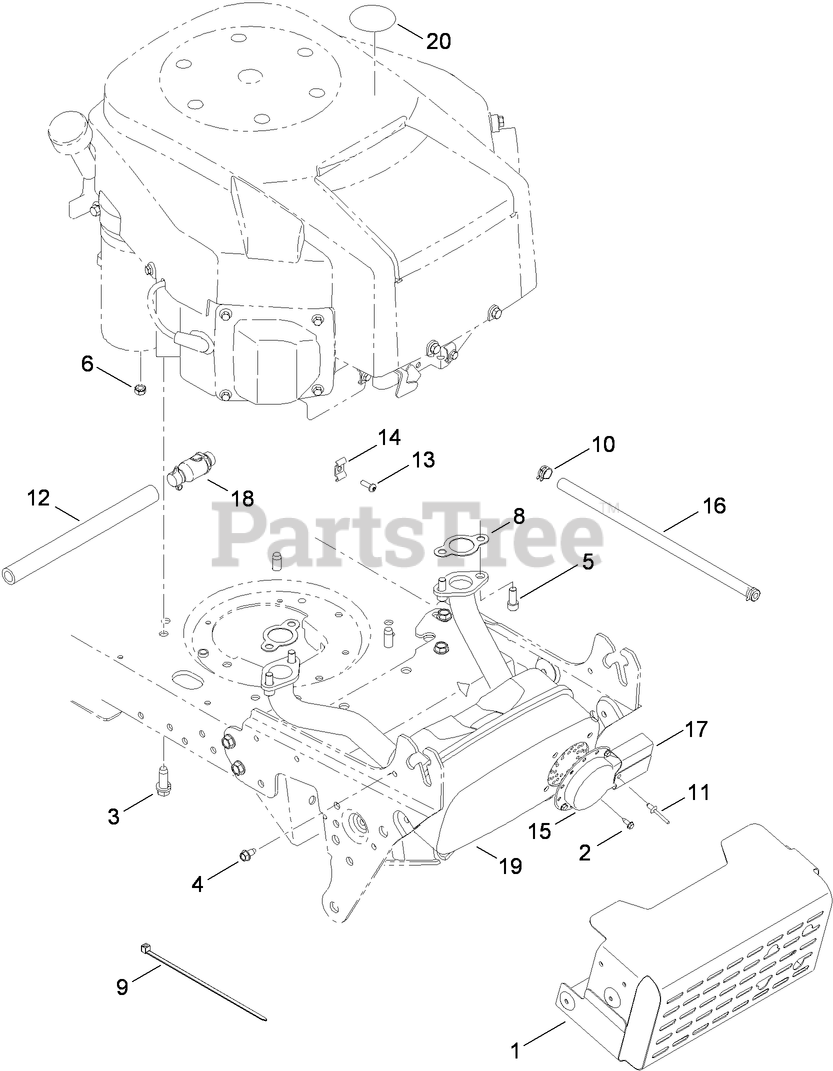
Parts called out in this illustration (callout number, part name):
1	SHIELD-MUFFLER
2	SCREW-HWHTF
3	SCREW-HH, TAP
4	SCREW-HWHTF
5	SCREW-HSH
6	NUT-SEMS
8	GASKET-EXHAUST
9	TIE-CABLE
10	CLAMP-HOSE
11	RIVET-POP
12	HOSE-DRAIN
13	SCREW-TAP
14	CLAMP-DUAL
15	DEFLECTOR-MUFFLER
16	HOSE-FUEL
17	DEFLECTOR-MUFFLER, LONG
18	Drain-Oil
19	MUFFLER-TWIN
20	DECAL-CHECK OIL
